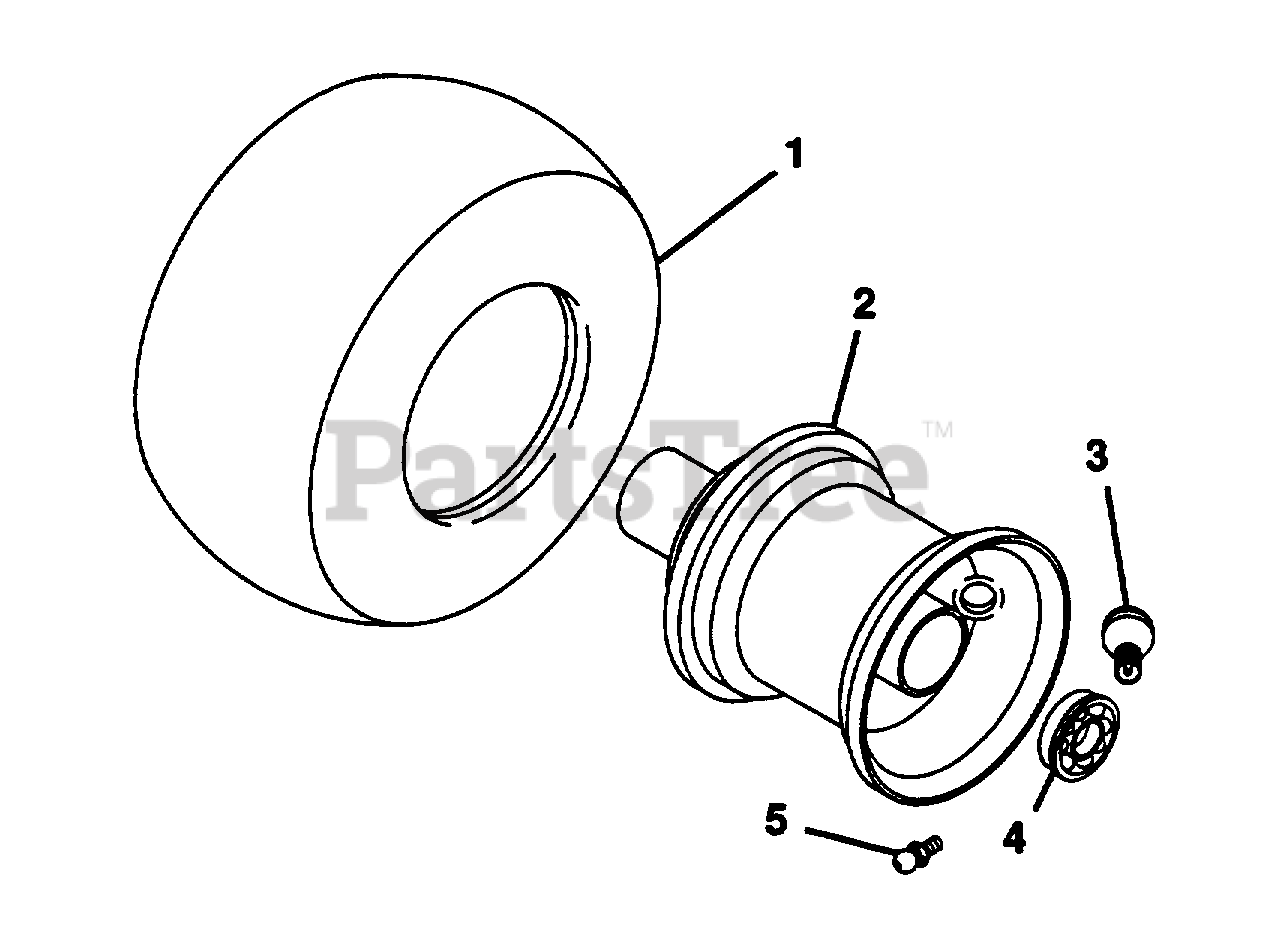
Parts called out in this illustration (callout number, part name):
1	TIRE, 13X5.00-6
2	ASSEMBLY, RIM
3	ASSEMBLY, VALVE STEM
4	BEARING, BALL
5	FITTING, LUBE 1/4-28
